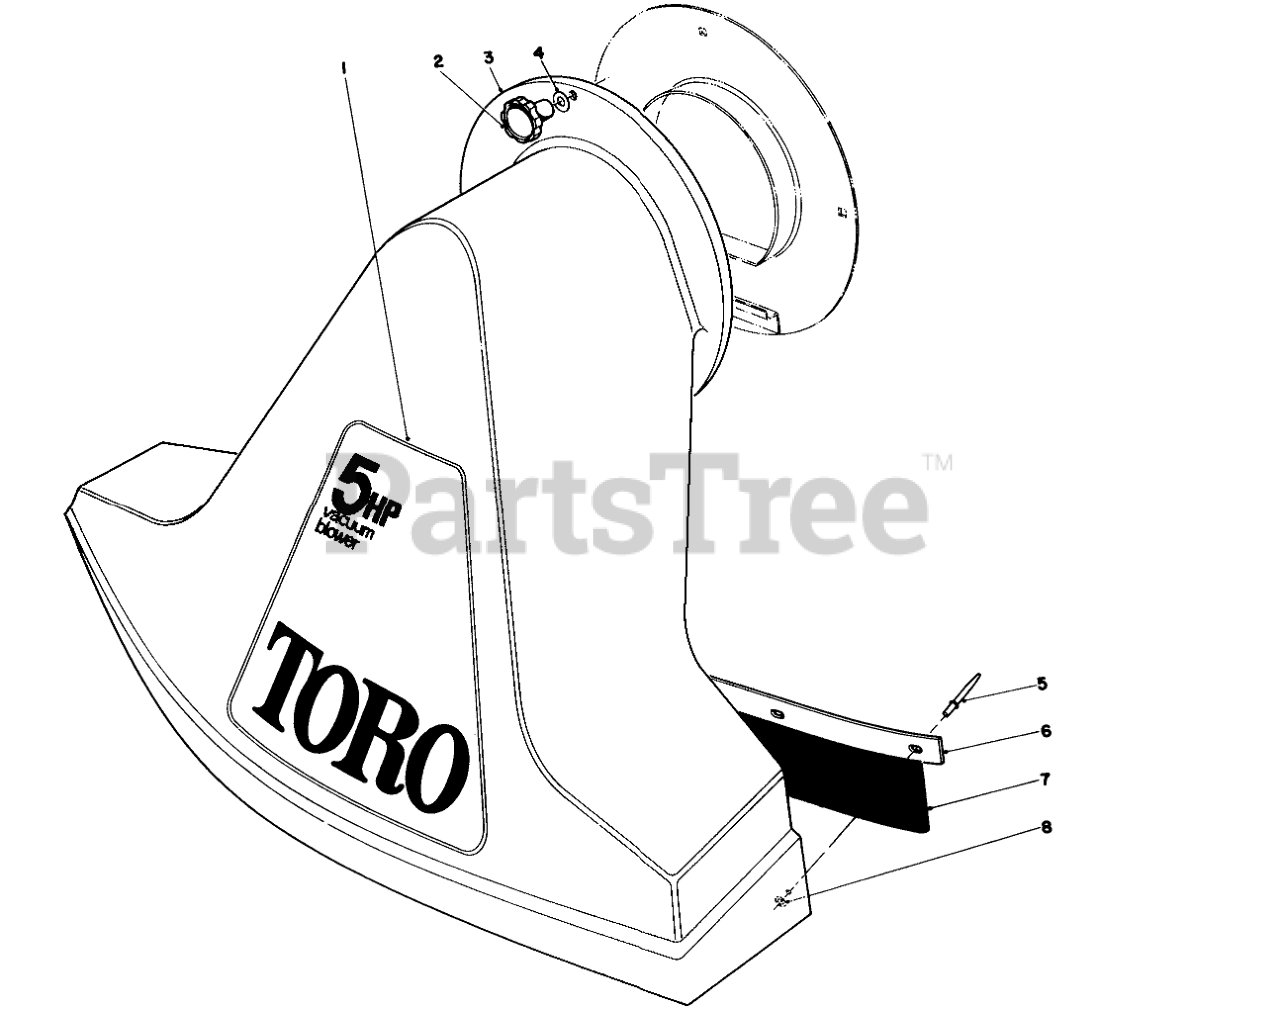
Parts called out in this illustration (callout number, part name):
1	Decal-Toro Model No. 62912
3	Snout Assembly (Incl. Ref. #5-8)
4	Washer
5	POP RIVET 3/16X.375LG
6	Clamp-Flap
7	FLAP-RUBBER
8	WASHER-FLAT
